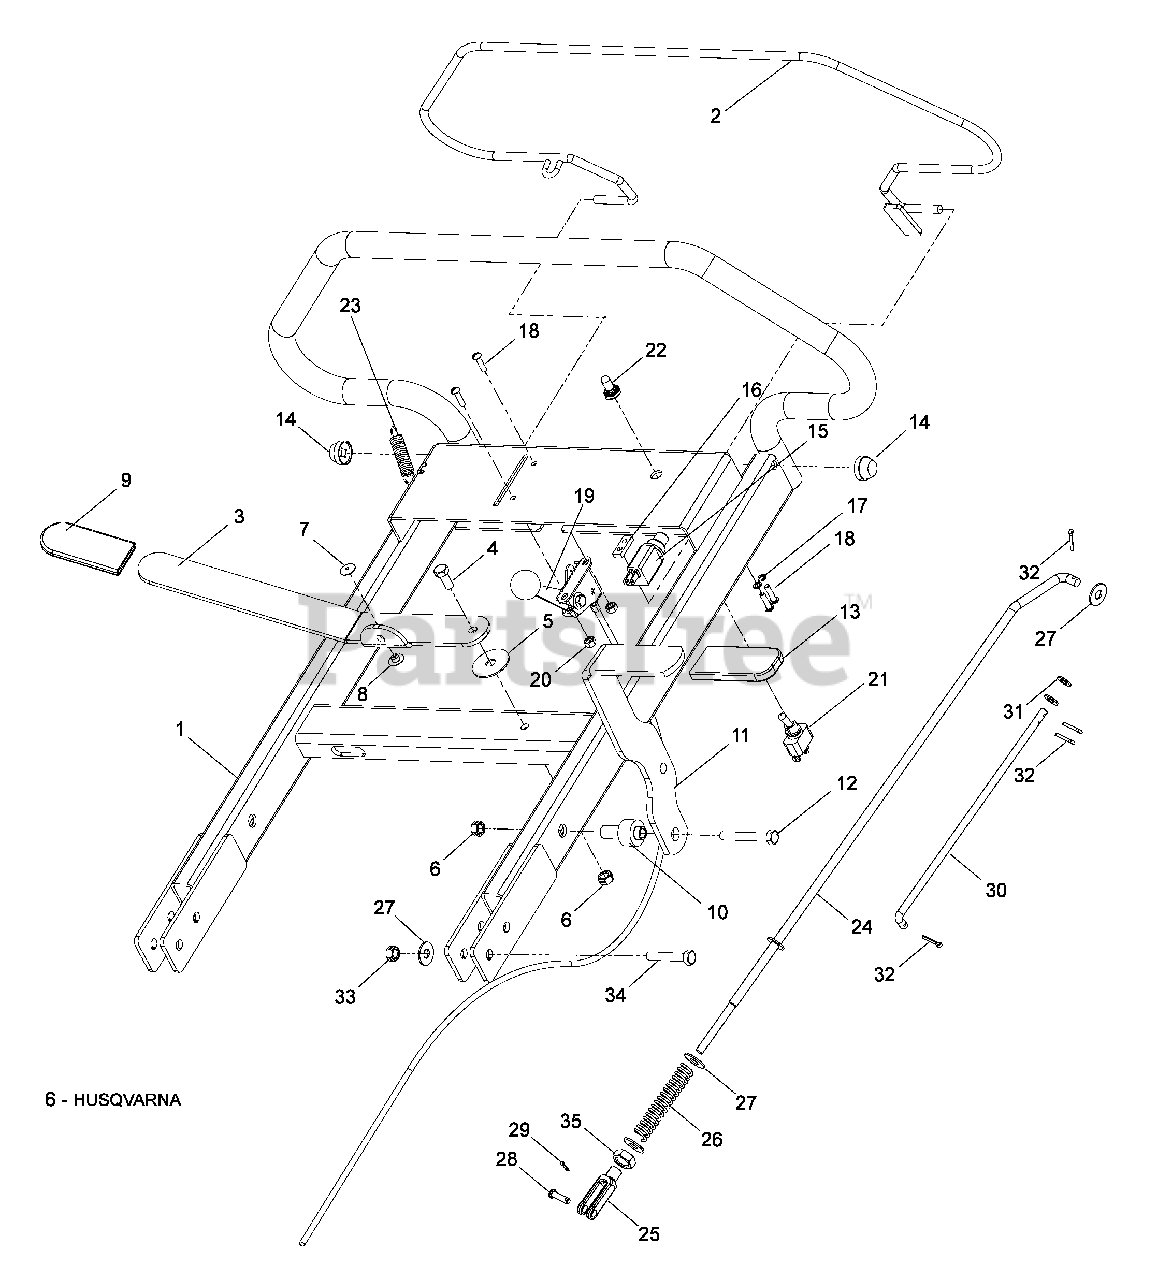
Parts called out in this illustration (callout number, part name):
1	HANDLE UPPER
3	HANDLE, POSITION ADJ
4	HCS 5/16-18 x ¾
5	WASHER, FRICTION
6	NUT 5/16-18 CNTRLK
7	RIVET, SNAP, MALE
8	RIVET, SNAP, FEMALE
10	BUSHING, STEP ¾ ID
11	HANDLE, WHEEL BRAKE
12	HCS 5/16-18 x 2¼
13	GRIP, PARK BRAKE
14	NUT 5/16 PUSH CAP
15	SWITCH, NC
16	PLATE, TAPPED
17	LOCKWASHER #10
18	SCREW #10-24 x ¾
19	THROTTLE CNTRL w/ KNOB
20	NUT #10-24 NYLOC
21	SWITCH, TOGGLE
22	BOOT, TOGGLE SWITCH
23	SPRING
24	ROD, PARK BRAKE
25	YOKE, 5/16
27	WASHER 3/8 FLAT STD
28	PIN, CLEVIS ¼ x 7/8
29	HAIRPIN COTTER
31	WASHER 5/16 SAE
32	PIN, COTTER 1/8 x ¾
33	NUT 3/8-16 CNTRLK
34	HCS 3/8-16 x 2
35	NUT 5/16-24 NYLOC
